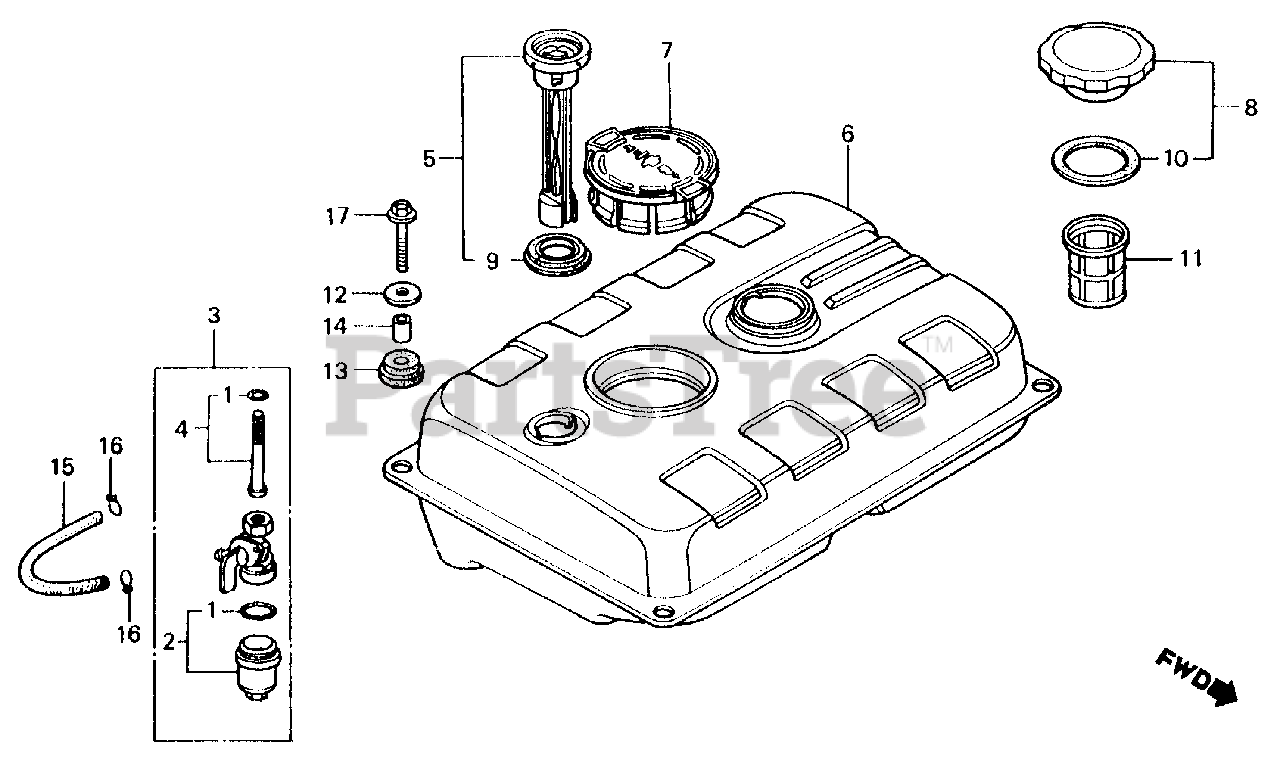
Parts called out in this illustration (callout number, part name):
1	GASKET SET, PETCOCK (CONTAINS 1 LARGE & 1 SMALL. USE AS NEEDED)
2	CUP, FUEL STRAINER
3	PETCOCK ASSY.
4	SCREEN SET
6	TANK, FUEL *R8* (BRIGHT RED) (NOT AVAILABLE)
7	CAP, SPARK PLUG HOLE
8	CAP, FUEL TANK
10	GASKET, FUEL FILLER CAP
11	FILTER, FUEL
12	WASHER, TANK RUBBER
13	CUSHION, TANK RUBBER
14	COLLAR, TANK RUBBER
15	BULK HOSE, FUEL (4.5X3000) (4.5X120)
16	CLIP, TUBE (B8)
17	BOLT, FLANGE (6X25)
